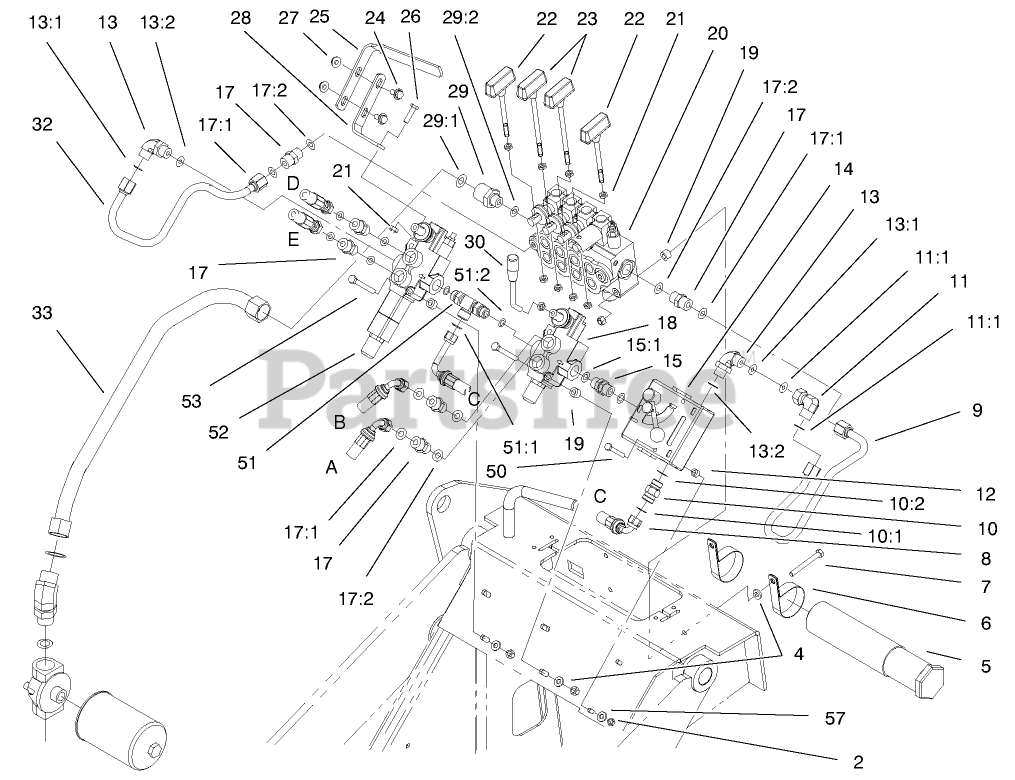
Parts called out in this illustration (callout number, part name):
2	NUT-LOCK, NI
4	WASHER-PLAIN
5	TUBE-MANUAL
6	CLAMP-R
7	SCREW-HH
8	HOSE ASM
9	TUBE-HYD
10	VALVE-CHECK, HYD
10:1	O-RING
10:2	O-RING
11	FITTING-HYD
11:1	O-RING
12	SPACER
13	FITTING-ELBOW-90 DEG
13:1	O-RING
13:2	O-RING
14	FLOW CONTROL VALVE
15	FITTING-THREAD, STRAIGHT
15:1	O-RING
17	FITTING-STRAIGHT
17:1	O-RING
17:2	O-RING
18	Valve-Hyd
19	SPACER
20	Valve-Hyd
21	NUT-HEX
22	CYLINDER HANDLE ASM
23	DRIVE HANDLE ASM
24	SCREW-HHF
25	GRIP-CONTROL
26	SCREW-HHF
28	MOUNT-CONTROL
29	FITTING-STR
29:1	O-RING
29:2	O-RING
30	LEVER-VALVE
32	HYD TUBE ASM
33	LINE - HYDRAULIC TANK
50	SCREW-HH
51	ADAPTER-TEE, ADJUSTABLE
51:1	O-RING
51:2	O-RING
52	Valve-Hyd
53	SCREW-HH
57	WASHER-FLAT
